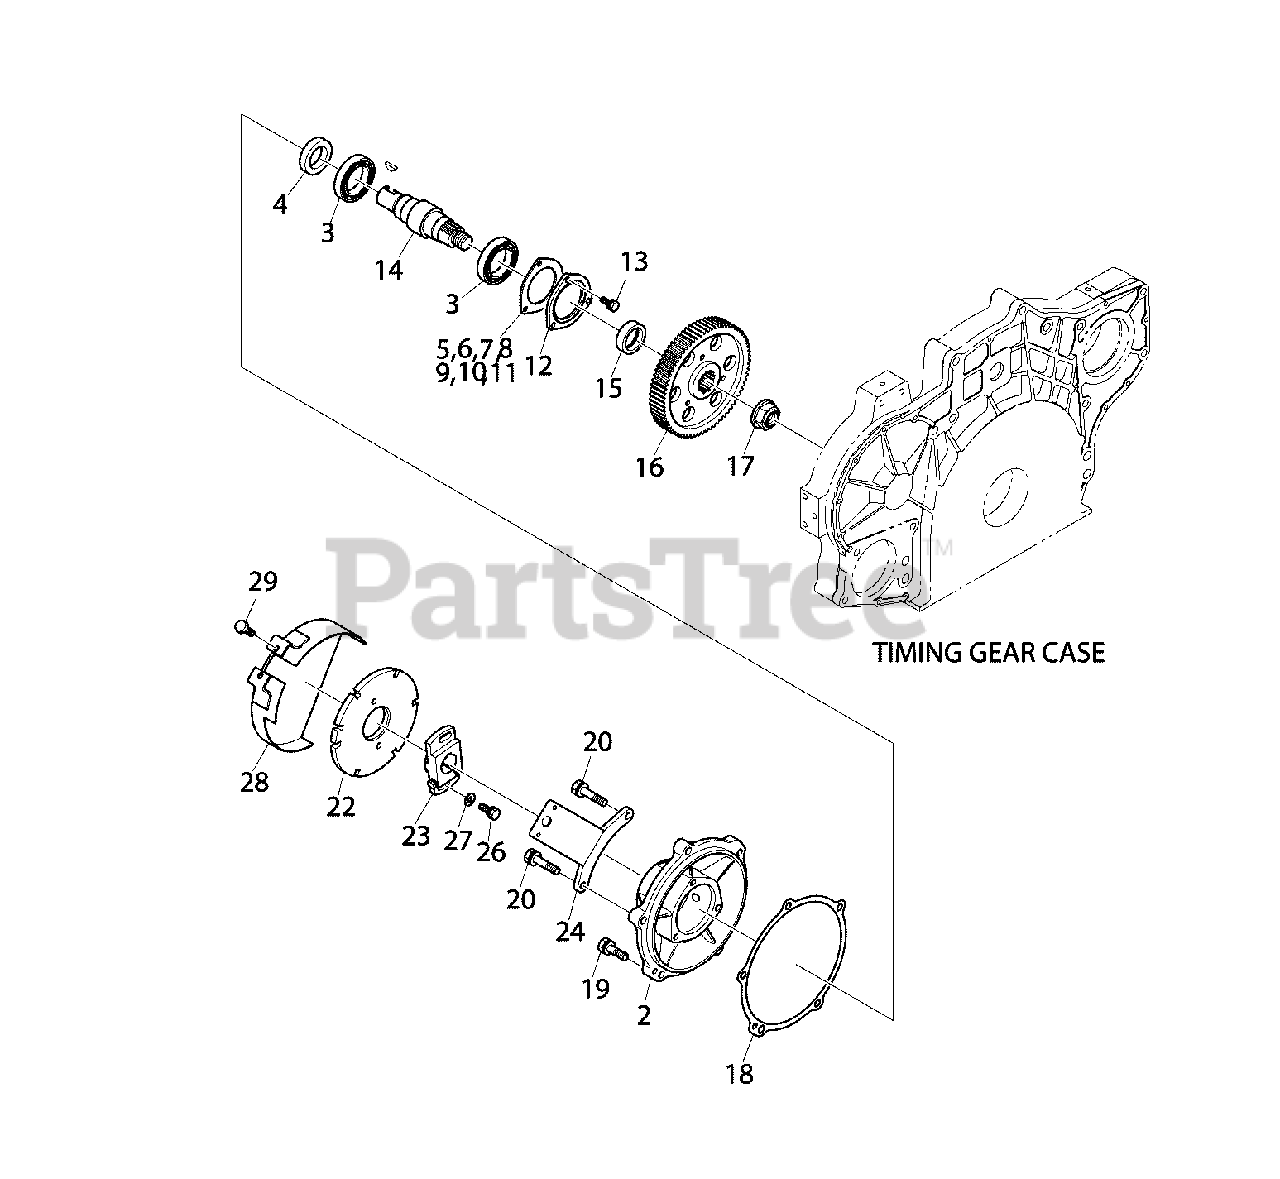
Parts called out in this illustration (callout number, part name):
2	* HOUSING
3	* BEARING, TAPPER
4	* SEAL, OIL
5	* SHIM (.33 MM) (AS NEEDED)
6	* SHIM (.20 MM) (AS NEEDED)
7	* SHIM (.15MM) (AS NEEDED)
8	* SHIM (.10 MM) (AS NEEDED)
9	* SHIM (.08 MM) (AS NEEDED)
10	* SHIM (.06 MM) (AS NEEDED)
11	* SHIM (.5 MM) (AS NEEDED)
12	* HOUSING, INJECTION PUMP DRIVE
13	* BOLT
14	* SHAFT, INJ DRIVE
15	* SPACER
16	* GEAR, INJ DRIVE
17	* NUT, LOCK
18	GASKET
19	* BOLT, HEX
20	* BOLT, HEX
22	* WHEEL, TIMING
23	* ADAPTOR, DRIVE
24	* BRACKET, CAM SENSOR
26	* BOLT
27	* WASHER
28	* COVER
29	* BOLT, HEX
